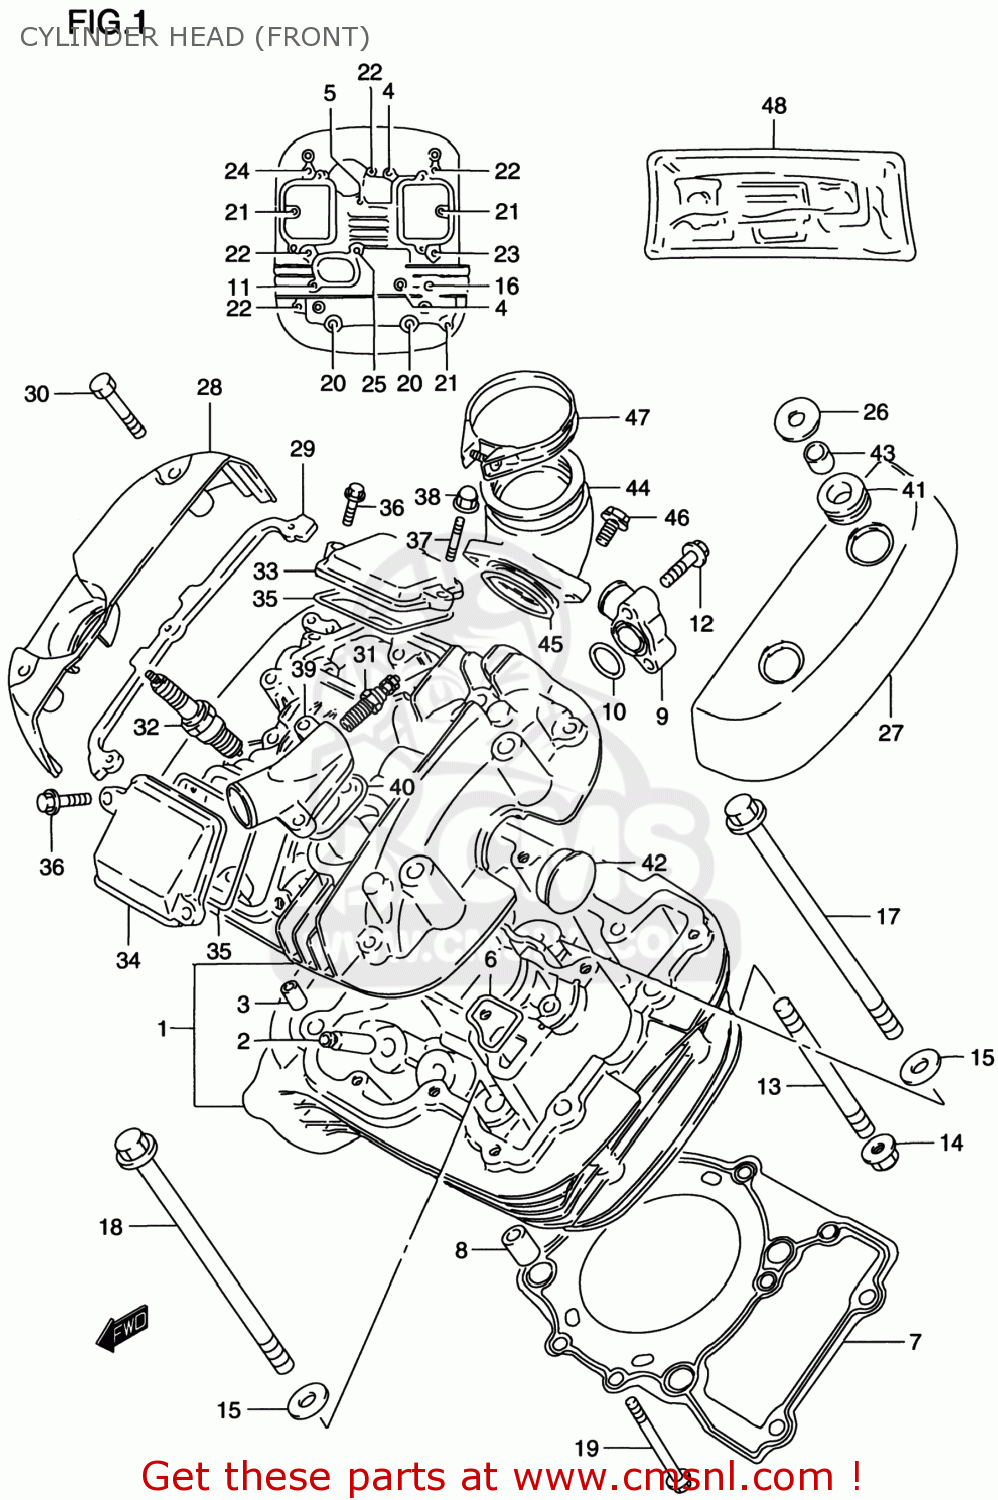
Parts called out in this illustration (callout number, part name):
1	HEAD ASSY,CYLINDER FR
2	GUIDE,VALVE
3	PIN(8.4X11X14)
4	BOLT(6X50)
5	BOLT(6X55)
6	GASKET,CYLINDER HEAD WATER (NAS)
7	GASKET,CYLINDER HEAD FR (NAS)
8	PIN
9	UNION,CYLINDER HEAD WATER
10	O RING(D:2.4,ID:17.8)
11	BOLT
12	SCREW
13	BOLT,STUD
14	NUT
15	WASHER (10.5X22X2.3)
16	BOLT(8X140)
17	BOLT(10X155)
18	BOLT(10X165)
19	BOLT
20	BOLT(8X245)
21	BOLT
22	BOLT
23	BOLT
24	BOLT
25	BOLT(6X55)
26	WASHER(8.5X24X1.6)
27	CAP,CYLINDER HEAD COVER FR,L
28	CAP,CYLINDER HEAD COVER FR,R
29	CUSHION,FR,R CAP
30	BOLT
31	GAUGE ASSY,WATER TEMP
32	PLUG,SPARK(DPR8EA-9)
33	CAP,INSPECTION INTAKE
34	CAP,INSPECTION EXHAUST
35	GASKET,INSPECTION CAP (NAS)
36	BOLT
37	STUD 6X16
38	NUT
39	UNION,WATER OUTLET
40	GASKET,WATER OUTLET UNION (NAS)
41	CUSHION
42	PLUG(OD:30)
43	BUSH
44	PIPE,INTAKE
45	O RING(D:2.4,ID:39.7)
46	BOLT
47	CLAMP
48	GASKET SET (NAS)
